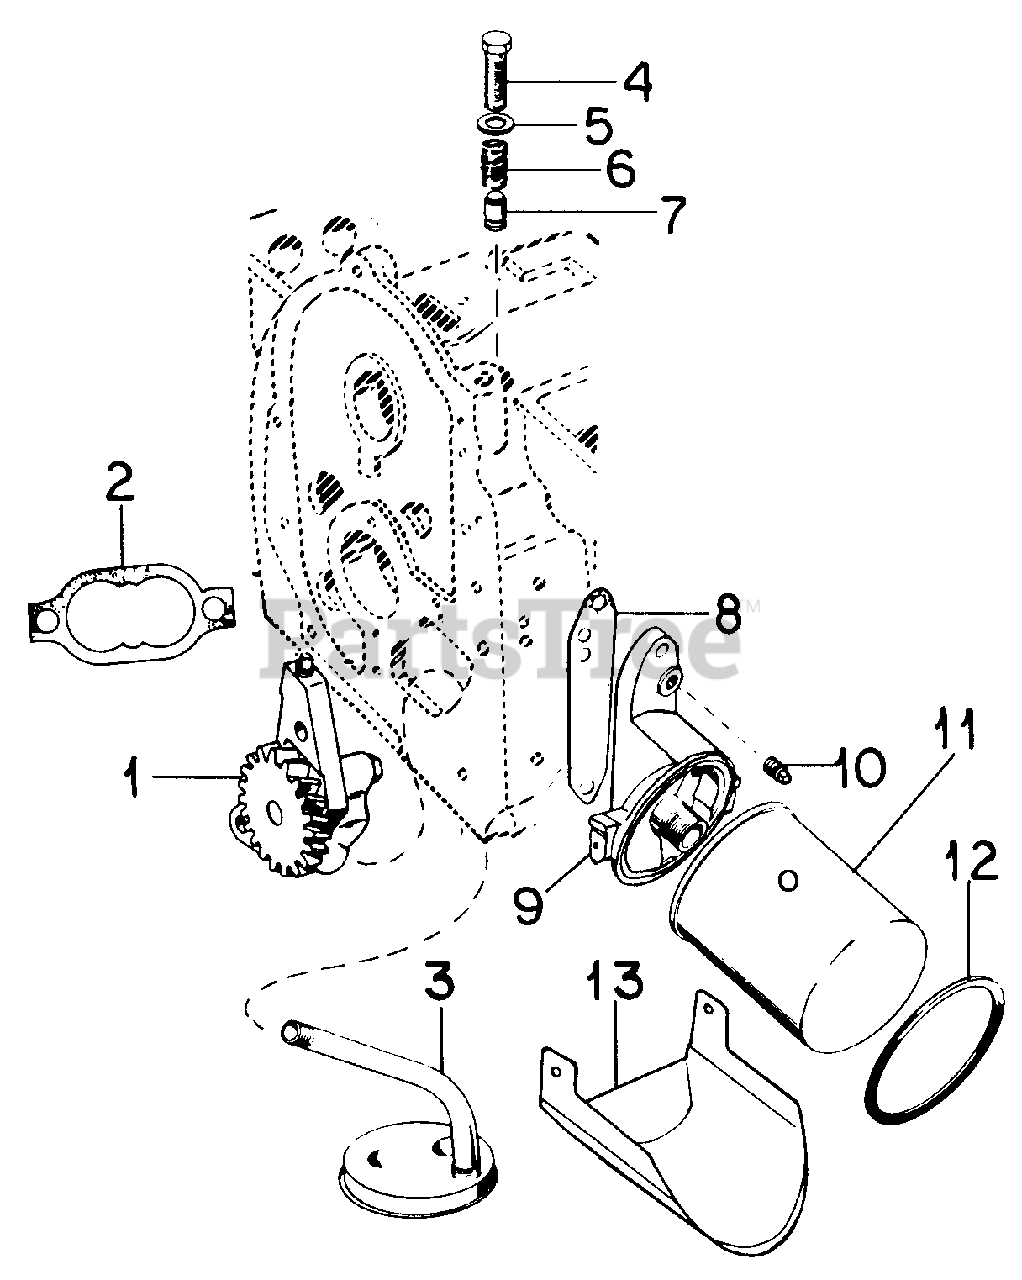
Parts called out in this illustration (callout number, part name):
2	Kit, Oil Pump Gasket
3	Cup, Oil Pump Intake
5	Washer, By-Pass Valve
6	Spring, By-Pass Valve
7	Valve, By-Pass
8	Gasket, Oil Filter Adapter Mtg
9	Adapter, Oil Filter
11	Filter, Oil
12	Seal, Air-Filter to Housing
13	Drain, Oil Filter
